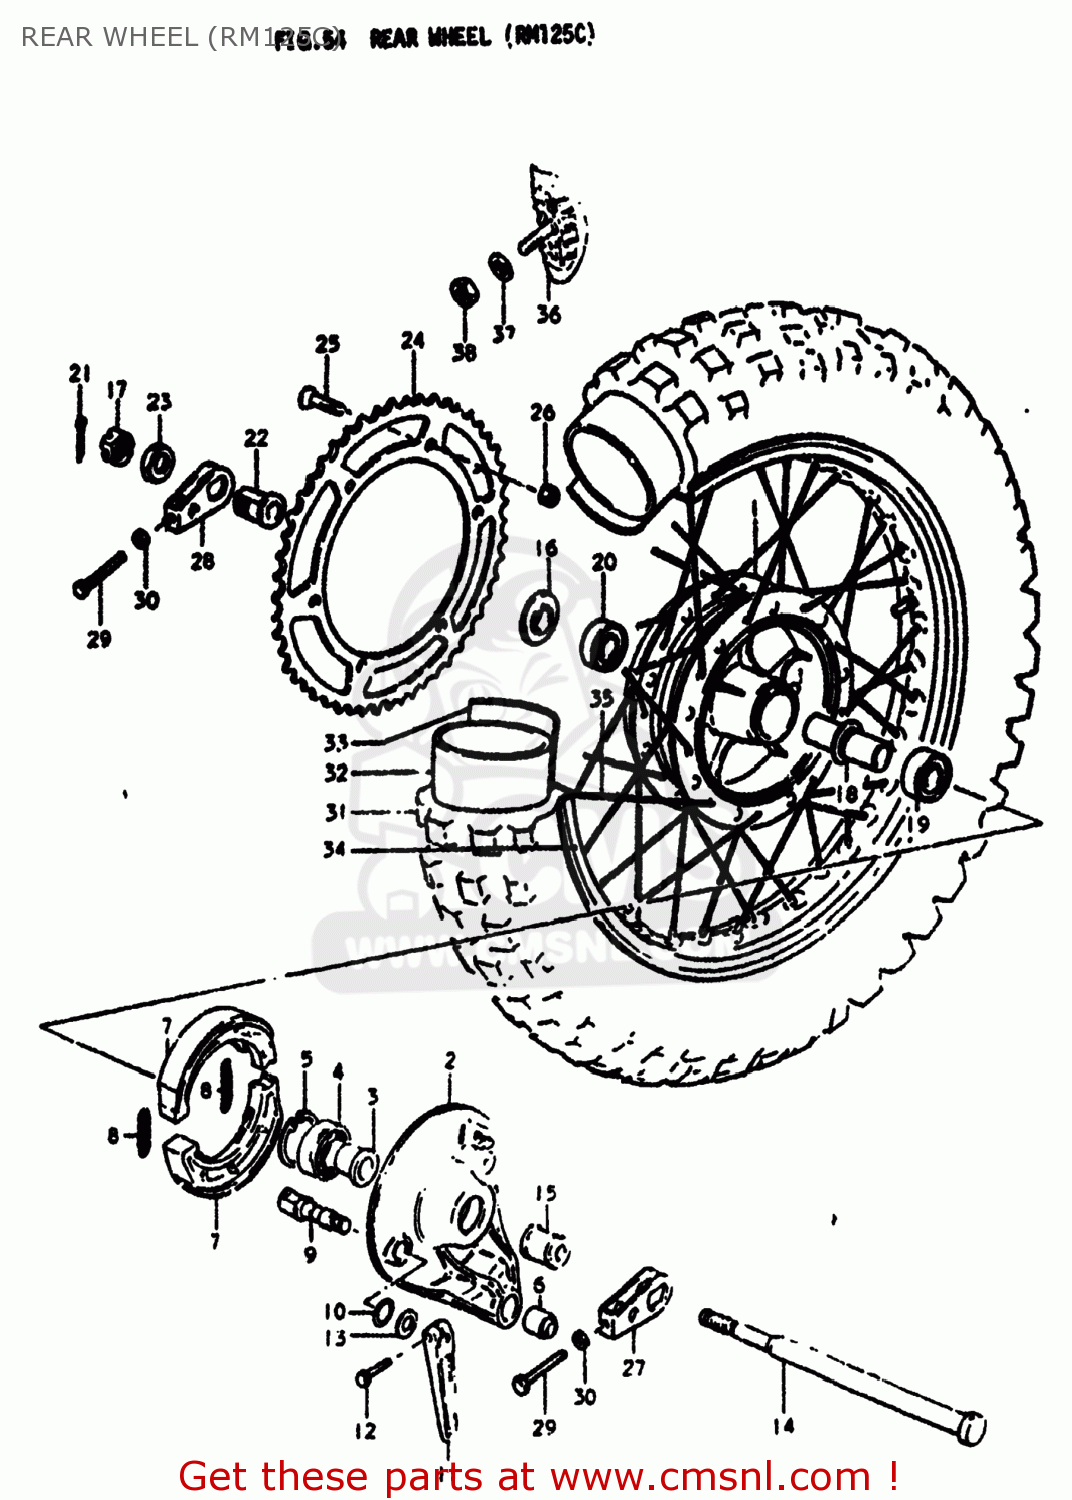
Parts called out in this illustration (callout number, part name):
1	HUB COMP,REAR
2	PANEL,REAR HUB
3	SPACER,REAR HUB PANEL
4	BALL BEARING
5	CIRCLIP
6	BUSH
7	SHOE,BRAKE
8	SPRING(L:34)
9	CAM,FR BRAKE
10	O RING(D:2.5,ID:11.4)
11	LEVER,FRONT BRAKE CAM
12	BOLT
13	WASHER(12.5X20X1)
14	AXLE,REAR
15	SPACER,REAR AXLE,RIGHT
16	SPACER,RR AXLE,L
17	NUT, REAR AXLE
18	SPACER,RR WHEEL HUB BEARING
19	BEARING
20	BEARING
21	COTTER PIN
22	SPACER,CHAIN ADJUSTER
23	NUT
24	SPROCKET,REAR
25	SCREW
26	NUT
27	ADJUSTER,CHAIN
28	ADJUSTER,CHAIN
29	BOLT(8X40)
30	NUT
31	TIRE
32	TUBE ASSEMBLY,WHEEL,INNER
33	PROTECTOR,WHEEL,INNER
34	RIM,REAR WHEEL
35	SPOKE SET,REAR
36	STOPPER,BEAD
37	WASHER
38	NUT
